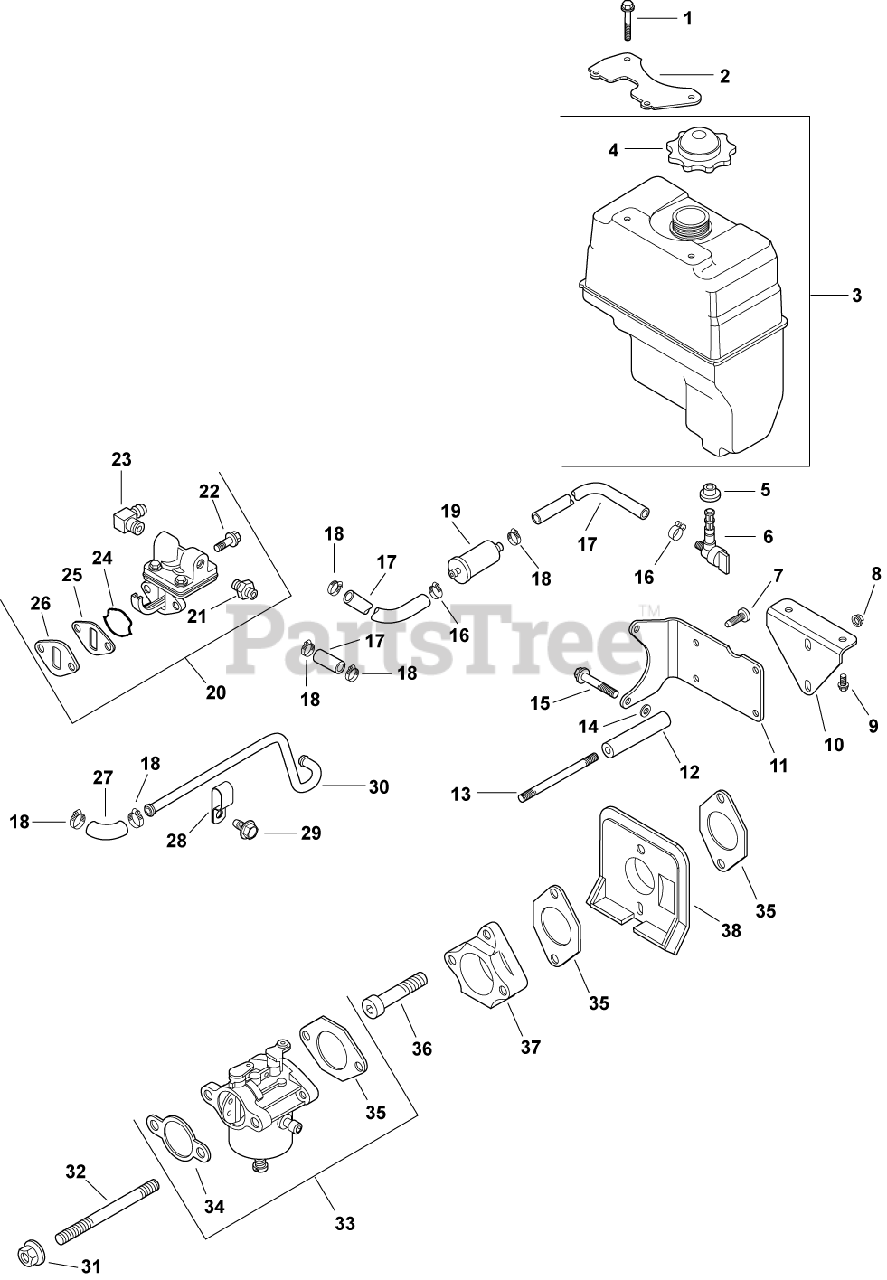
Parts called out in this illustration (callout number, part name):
1	SCREW,FLG THD FRM M6X1.0X25-(#25086395S)
2	BRACKET, FUEL TANK
3	KIT, FUEL TANK
4	CAP, FUEL TANK
5	BUSHING, FUEL TANK
6	VALVE, FUEL SHUT-OFF
7	SCREW, LBD SKT M6x1.0x20-(#25086403S)
8	NUT, FLG M8X1.25
9	SCREW, FLG M6X1.0X12
11	BRACKET, FUEL TANK
12	SPACER, FUEL TANK
13	STUD, M8X1.25X133-USE 25 755 54-S
14	WASHER, FLAT 11/32"
15	SCREW, FLG M8X1.25X50
16	CLAMP, BAND SPRING HOSE-(#2523737S)
17	HOSE,LW PERM.FUEL 24.00"-USE 25 111 81-S
18	CLAMP, HOSE (KM)-USE 25 237 31-S
19	FILTER,FUEL 51 MICRON (FUEL PUMP)
20	KIT, FUEL PUMP
21	KIT, STRAIGHT FITTING
22	SCREW,FLG THD FRM M6X1.0X20-(#25086396S)
23	CONNECTOR, 90 DEG. HOSE
24	O-RING, FUEL PUMP
25	SPACER, FUEL PUMP
26	GASKET, FUEL PUMP
27	HOSE, FUEL LOW-PERMEATION
28	CLIP, TUBE & WIRING (KM)
29	SCREW, FLG THD FRM M5X.8X10
30	LINE, FUEL - DISCONTINUED
31	NUT, FLG M6X1.0
32	STUD,M6X1.0X116
33	KIT, CARBURETOR W/GASKET - (#DSC)
34	GASKET, AIR CLEANER BASE
35	GASKET, CARBURETOR
36	SCREW, SKT CAP M6X1.0X35
37	ADAPTER, CARBURETOR
38	DEFLECTOR, HEAT
